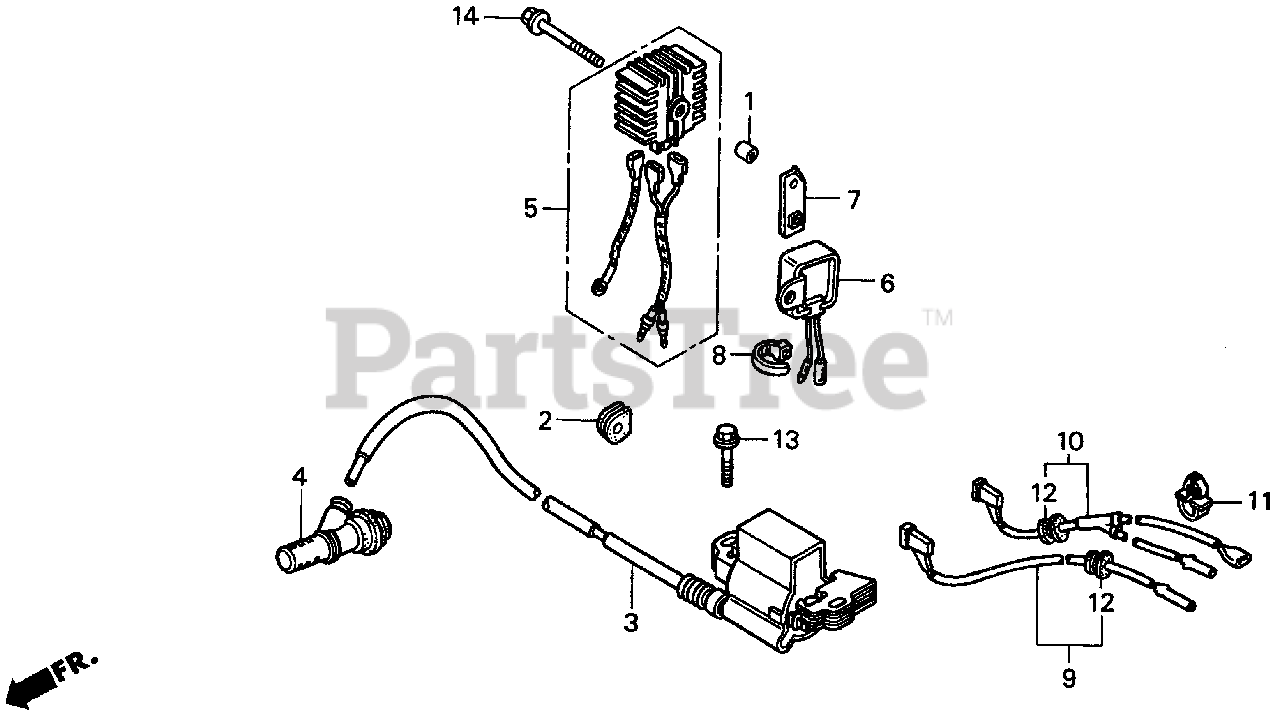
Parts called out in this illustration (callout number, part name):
1	SPACER, AIR CLEANER ELBOW
2	GROMMET, WIRE
3	COIL ASSY., IGNITION
4	CAP ASSY., NOISE SUPPRESSOR
5	RECTIFIER ASSY., SILICON
10	WIRE, STOP SWITCH
11	HOLDER, STOP SWITCH WIRE
12	GROMMET, WIRE
13	BOLT, FLANGE (6X28)
14	BOLT, FLANGE (6X40)
